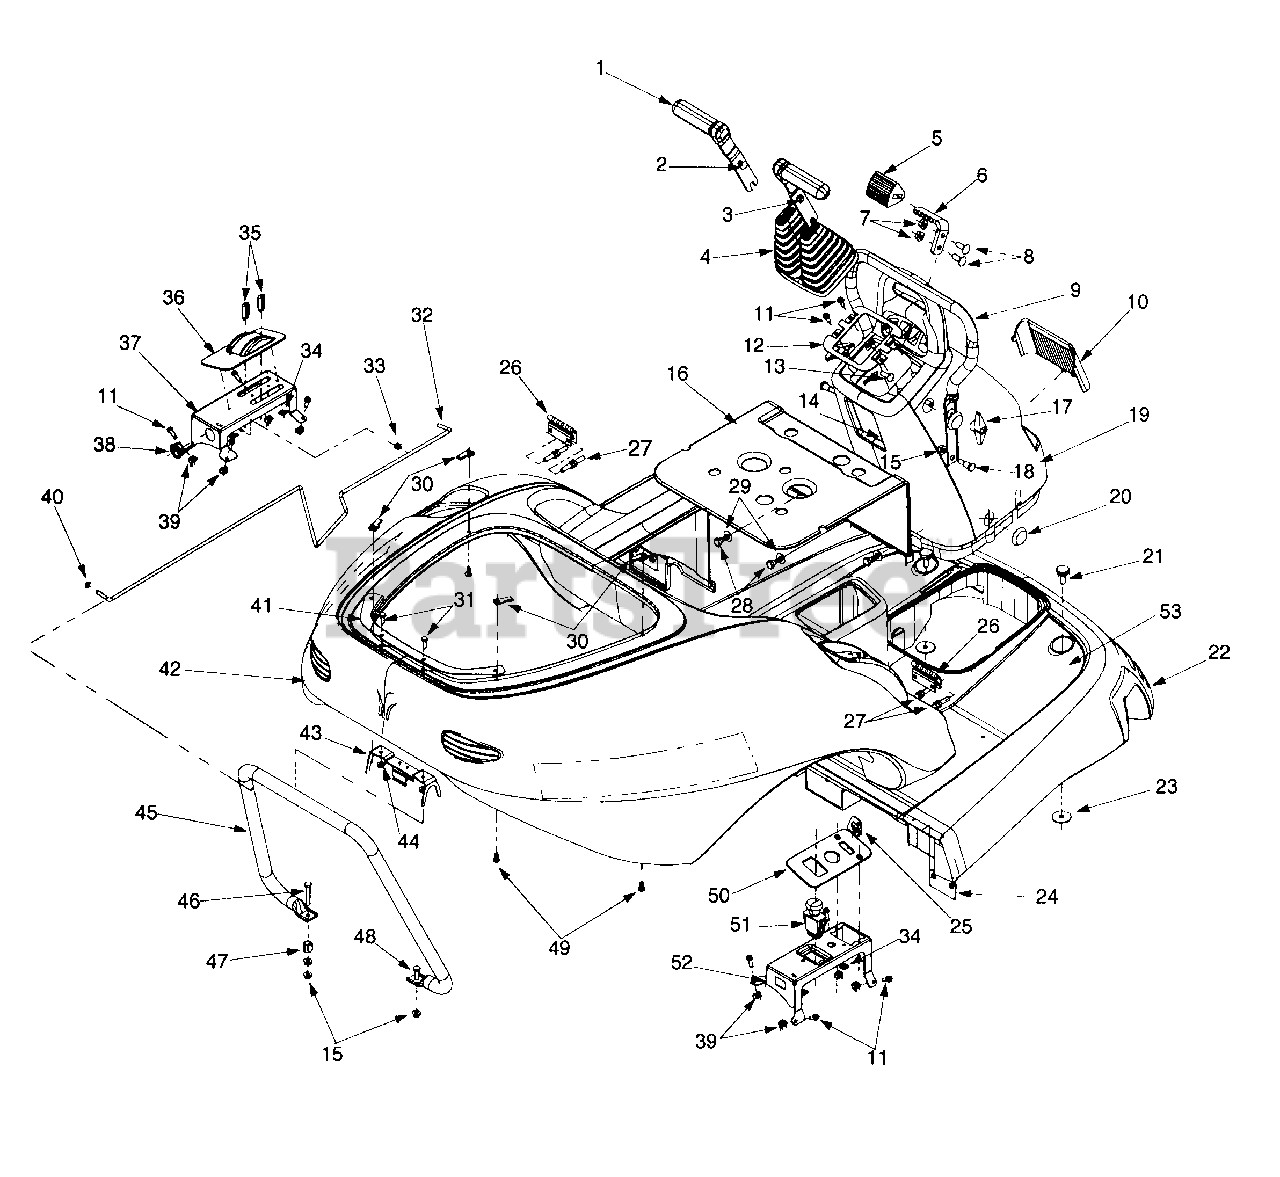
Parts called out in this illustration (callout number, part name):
1	Control Handle
2	Carriage Bolt 5/16-18 x .75
3	Flange Lock Nut 5/16-18
4	Control Bellow
8	Carriage Bolt 3/8-16
11	Hex Washer Screw 1/4-20 x .75
16	Seatbase Cover
17	Wingnut Knob Assembly 5/16-18
18	Shoulder Screw
21	Shoulder Screw 3/8-16 x .75
23	Flat Washer .406 ID x 1.5 OD
24	Body Plate Assembly
25	Key
26	Body Hinge
27	Hex Cap Screw 5/16-18 x 1.0
28	Shoulder Screw
29	Flat Washer .474 ID x .879 OD
30	U-Type Nut 1/4-20
31	Hex Cap Screw 1/4-20 x .75
32	Support Rod
33	Clip
34	Push Nut
35	Lever Knob
36	Control Panel Cover - LH
39	Retainer Nut 1/4-20
41	Latch Mounting Plate
42	Rear Body
43	Clip Spring Bracket Assembly
44	Lock Nut 1/4-20
48	Hex Cap Screw 5/16-18 x 1.0
49	Screw 1/4-20 x .625
50	Cover Panel - RH
51	Electric Switch PTO
